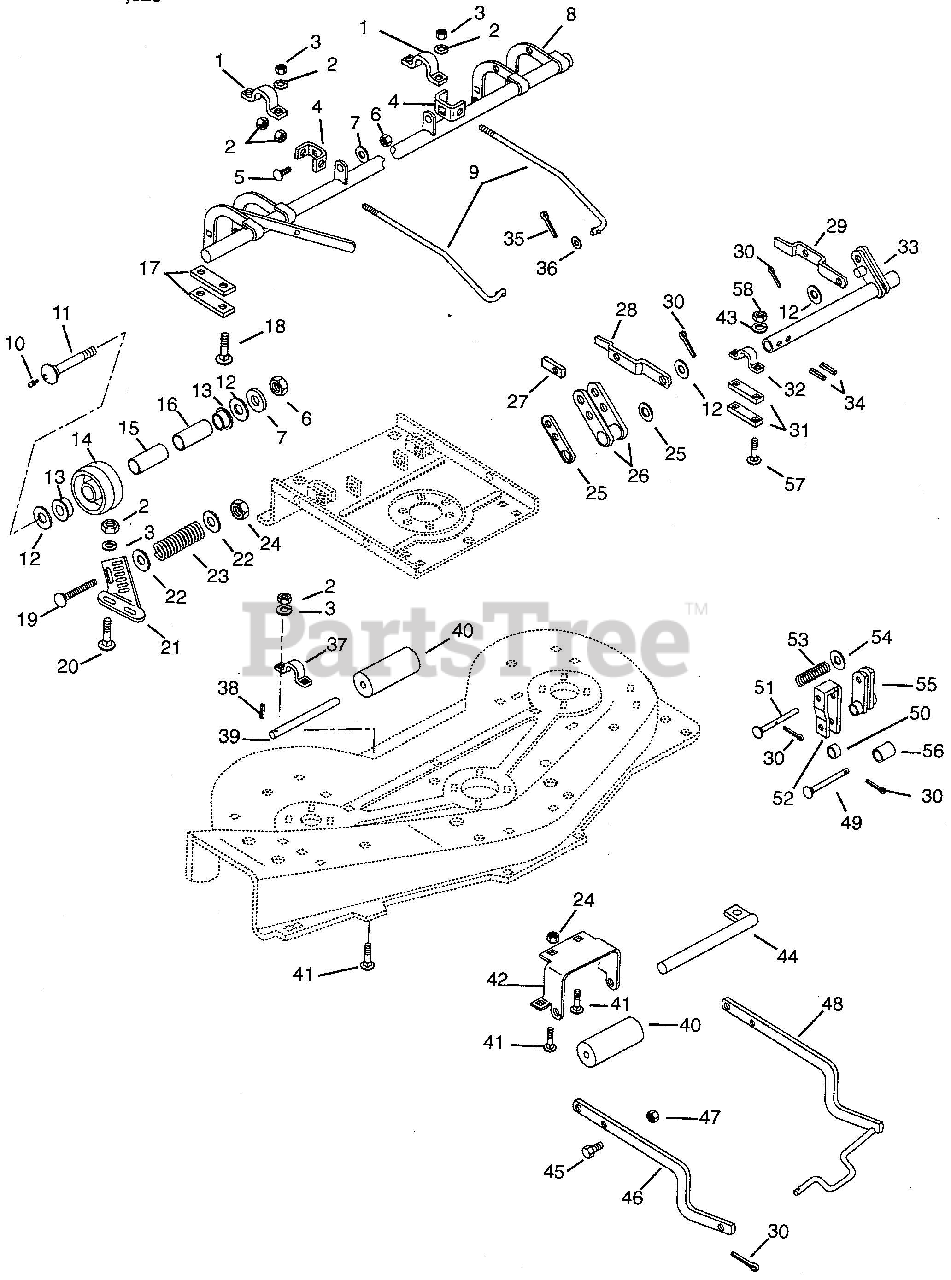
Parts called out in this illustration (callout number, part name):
2	@NUT-HEX .31-18 YWZC
3	@WSHR-LK .31X.078 REG YWZC
5	BLT-RDHDSQNK .50-13X1.25 G2YW
6	@NUT-LK-CTR .50-13 YWZC
7	WSHR-FL-STL .505X.880X.072 YWZ
8	ROLLER FRAME
9	ADJUSTMENT ROD
10	FTG-LUBE .25-28X.256 YWZC
11	WHEEL BOLT W/ZERK
12	WSHR-FL-STL.511X1.441X.125 YWZ
13	BRG-BALL .500X1.125X.500
14	WHL 5 IN O.D.
15	WHEEL HUB
16	SPACER .512X.747X3.396
18	@BLT-RDHDSQNK .31-18X1.00 G5YZ
19	@BLT-RDHDSQNK .31-18X1.75 G5YZ
20	BLT-RDHDSQSHK.31-18X.75 GR2 YW
21	QUADRANT
22	@WSHR-FL-STL.38X.875X.083 YWZC
23	SG-COMP .063X.53X1.187
24	@NUT-LK-CTR .31-18 YWZC
25	WSHR-FL-STL.755X1.375X.062YWZC
26	FRONT HANGER LINK
27	WEAR PLATE
28	LEVELING LEVER R.H.
29	LEVELING LEVER L.H.
30	@PIN-CTR .12X1.00 EXTPRSQCT YZ
33	FRONT HANGER
34	PIN-ROLL .250X1.25
35	@PIN-CTR .12X.75 EXTPRSQCT YWZ
36	@WSHR-FL-STL.50X1.25X.083 YWZC
37	ROLLER CLAMP
38	PIN-ROLL .250X1.00
41	@BLT-RDHDSQNK .31-18X.75 G5YZ
42	BRACKET, ROLLER
43	@WSHR-LK .50X.125 REG YWZC
44	ROLLER SHAFT
45	@BLT-HEX .38-16X1.00 GR5 YWZC
46	HANGER ARM
47	@NUT-LK-CTR .38-16 YWZC
48	MOWER HANGER
49	PIN-CLEV .498X4.50 YWZC
50	SPACER .390X1.000X.562
51	PIN-CLEV .498X4.31 YWZC
52	SUPPORT CHANNEL
53	SG-COMP .62X.68X1.75
54	@WSHR-FL-STL.531X1.06X.095YWZC
55	ARM
56	SPACER .516X.749X.938
57	@BLT-RDHDSQNK .50-13X1.50 G5YZ
58	@NUT-HEX .50-13 YWZC
